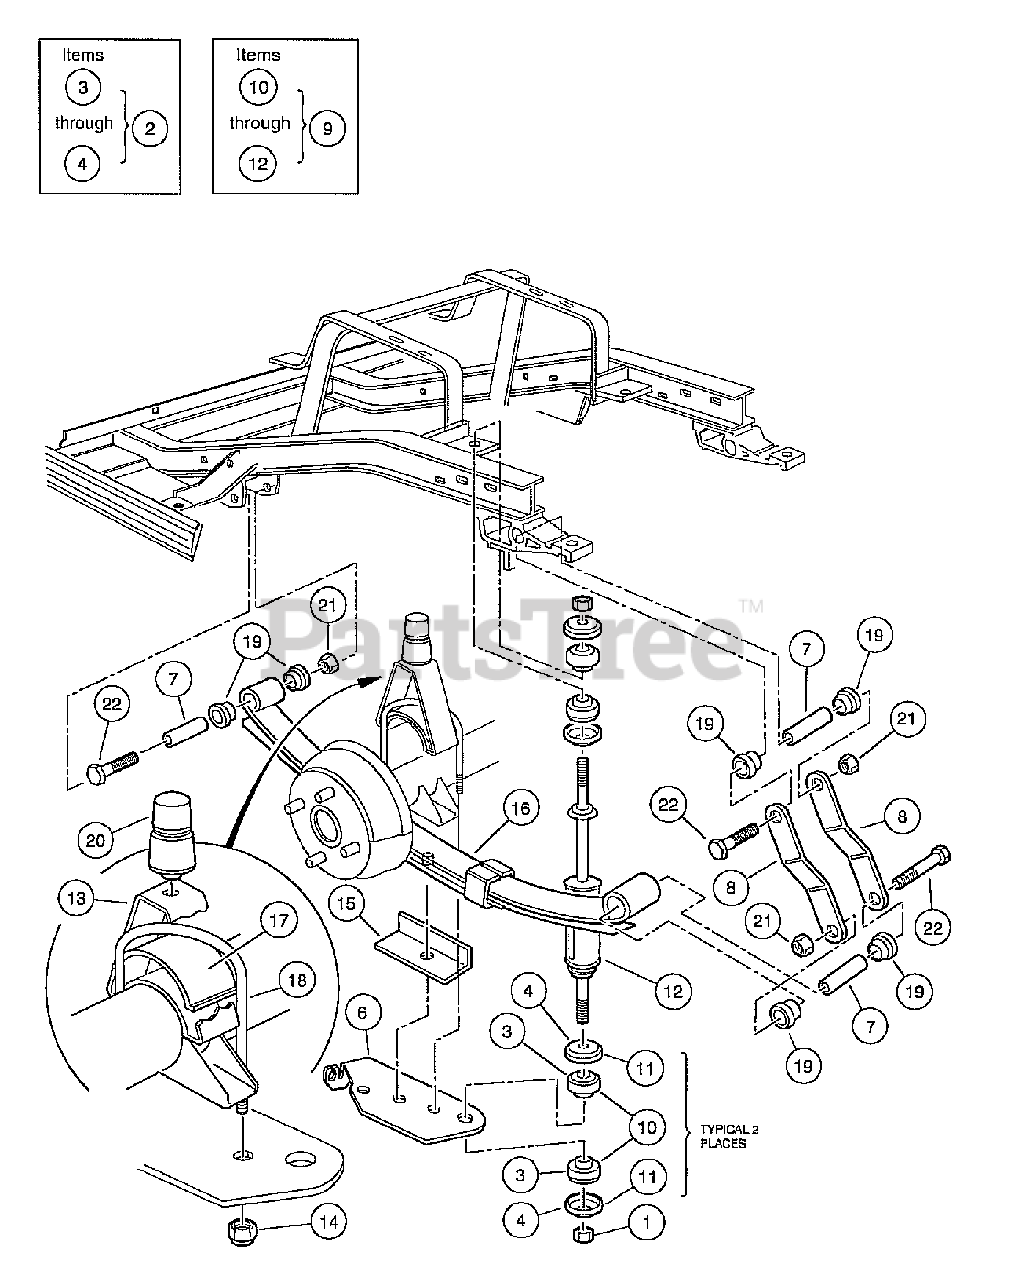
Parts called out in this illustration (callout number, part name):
1	Nut, 3/8-24 Hex
2	Kit, Shock Absorber Cushion
3	Cushion, Shock Absorber
4	Retainer, Shock Absorber Cushion
5	Bracket, Shock Mounting, Right (Passenger)
6	Bracket, Shock Mounting, Left (Driver)
7	Bushing, Steel
8	Shackle, Rear Spring
9	Shock Absorber Kit
10	Cushion, Shock Absorber
11	Retainer, Shock Absorber Cushion
12	Shock Absorber Rear
13	Bumper Mount, Angled
14	Locknut, 7/16-14 Nylon Insert
15	Spring Retainer
16	Rear Leaf Spring
17	Spacer, Overload Bumper
18	U-Bolt
19	Bushing, Urethane
20	Bumper, Jounce
21	Locknut, 3/8-16 Hex
22	Screw, 3/8-16 X 3.375 Hex Cap
